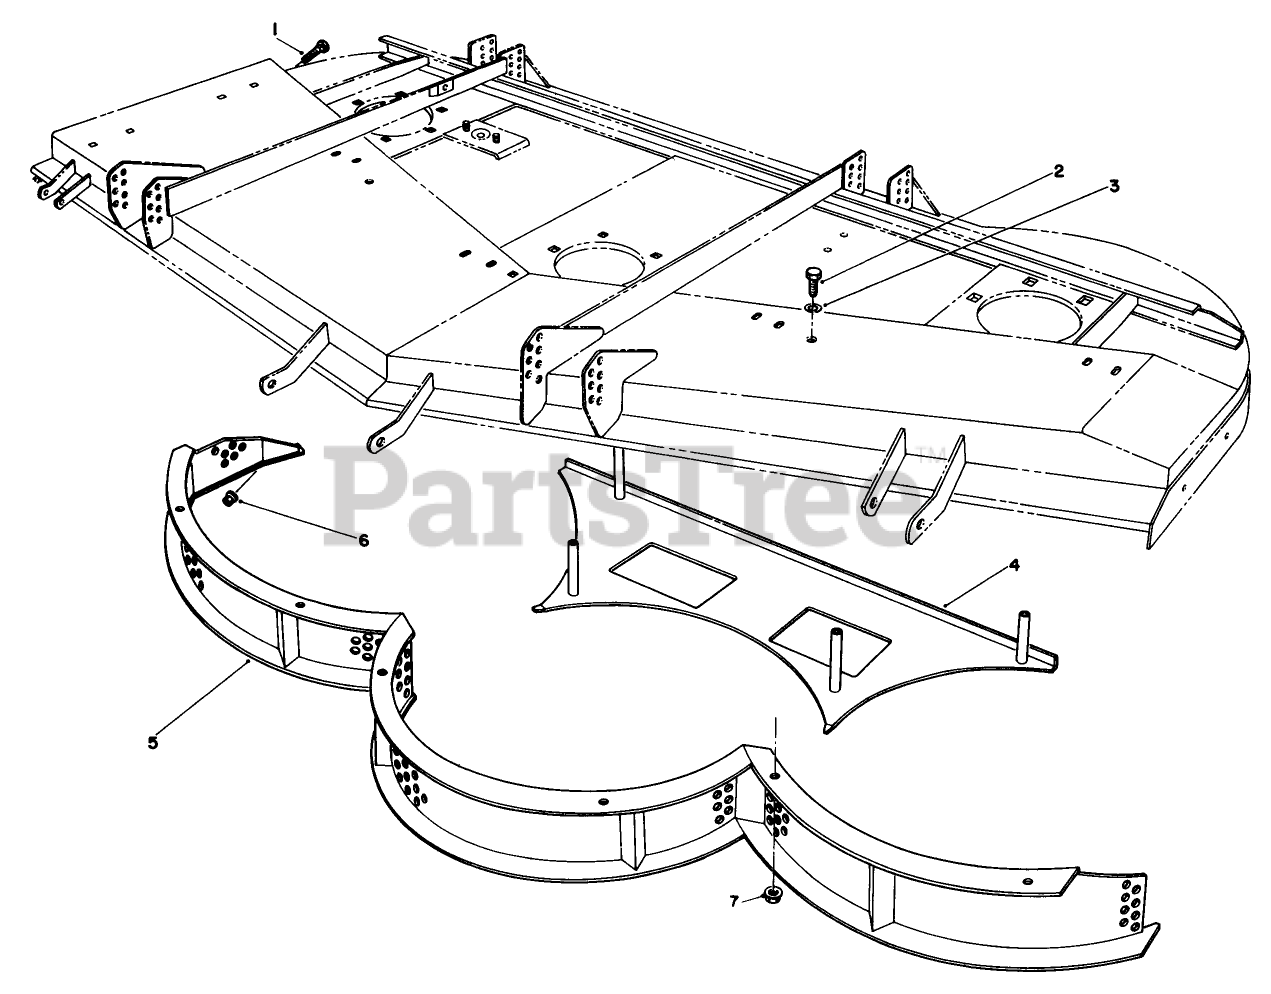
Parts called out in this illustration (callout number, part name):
1	BOLT-CARR
2	SCREW-HH
3	WASHER-LOCK
4	Shelf
5	Screen W.A.
6	NUT-HF
7	NUT-HHF, WHIZ
